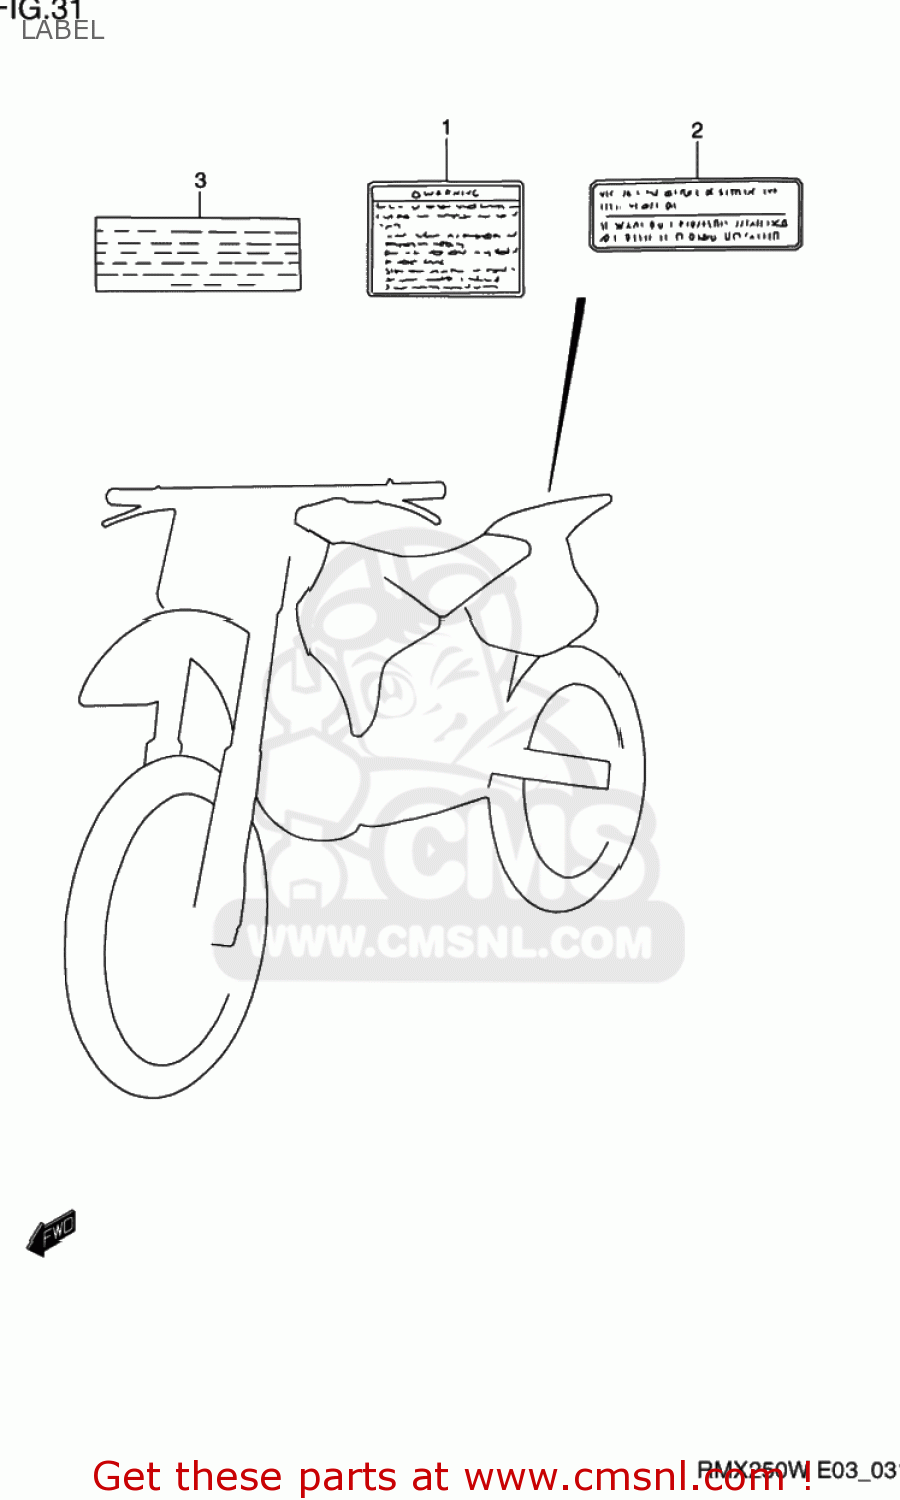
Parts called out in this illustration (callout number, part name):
1	LABEL (WARNING SAFETY),E
2	LABEL,WARNING NO.2
3	LABEL (MANUAL NOTICE)
4	MANUAL, OWNER'S
